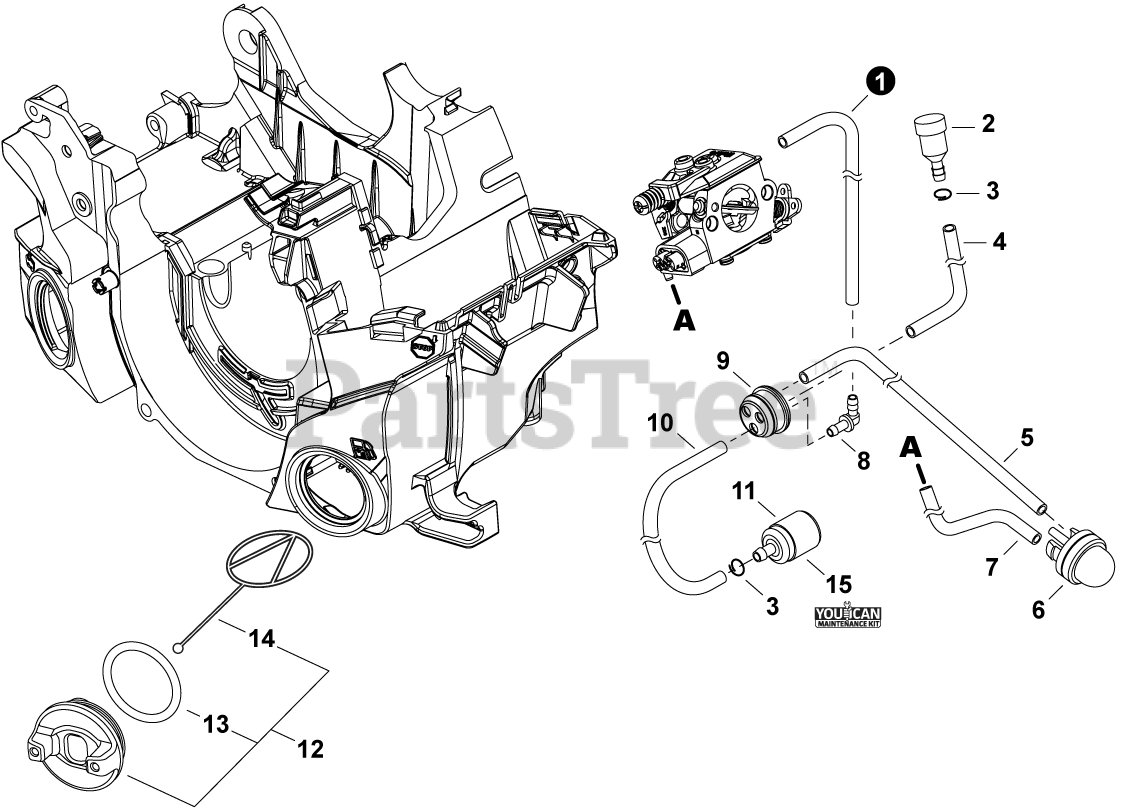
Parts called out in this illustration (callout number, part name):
1	PIPE, FUEL 3×5×85 BLACK
2	VENT ASSY
3	CLIP Ø6
4	PIPE, FUEL 3×5×70 BLACK
5	PIPE, PURGE 2.5×5×140
6	BULB, PURGE
7	PIPE 2.4×5×105 BLACK
8	CONNECTOR, PIPE
9	GROMMET, FUEL Ø5
10	PIPE, FUEL 3×5×120 BLACK
11	FILTER, FUEL
12	CAP ASSY, FUEL
13	O-RING 29
14	FUEL CAP CONNECTOR (L=60MM)
15	TUNE-UP KIT - YOUCANT
